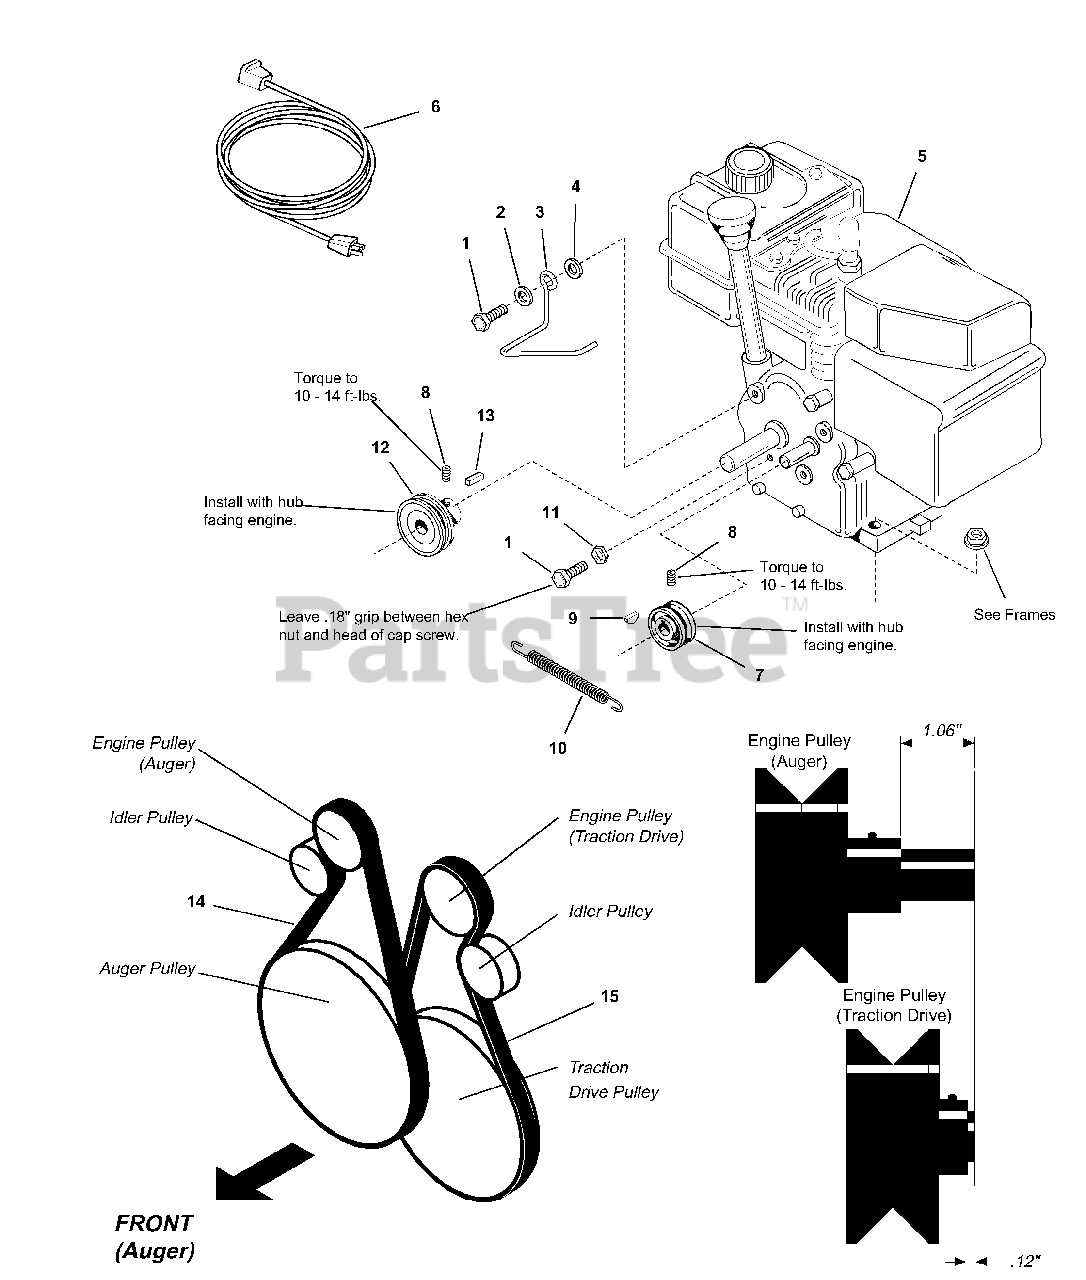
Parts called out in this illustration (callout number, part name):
1	CAPSCREW, Hex Hd., 5/16-24 x 3/4
2	WASHER,
4	LOCKWASHER-EXTERNAL TOOTH .375
5	555M 5 HP ENGINE, Tecumseh, manual start,`
5	755M 7 HP ENGINE, Tecumseh, electric start
5	755M 7 HP OHV ENGINE, Tecumseh, manual start
5	755M 7 HP ENGINE, Tecumseh, manual start
6	CORD, Electric Start
7	PULLEY, Engine - Traction Drive,
8	SCREW, Set, Hex Socket Cup Pt. 5/16-18 x 5/16
9	KEY, Hi-Pro, 1/8x 5/8
10	SPRING, Extension,
11	NUT, Hex, Jam, 5/16-24
12	PULLEY, Engine - Auger Drive,
13	KEY, Parallel, 3/16 x 3/16
14	V-BELT, 4L, Auger Drive
15	V-BELT, 3L Traction Drive,
15	V-BELT, 3L Traction Drive
